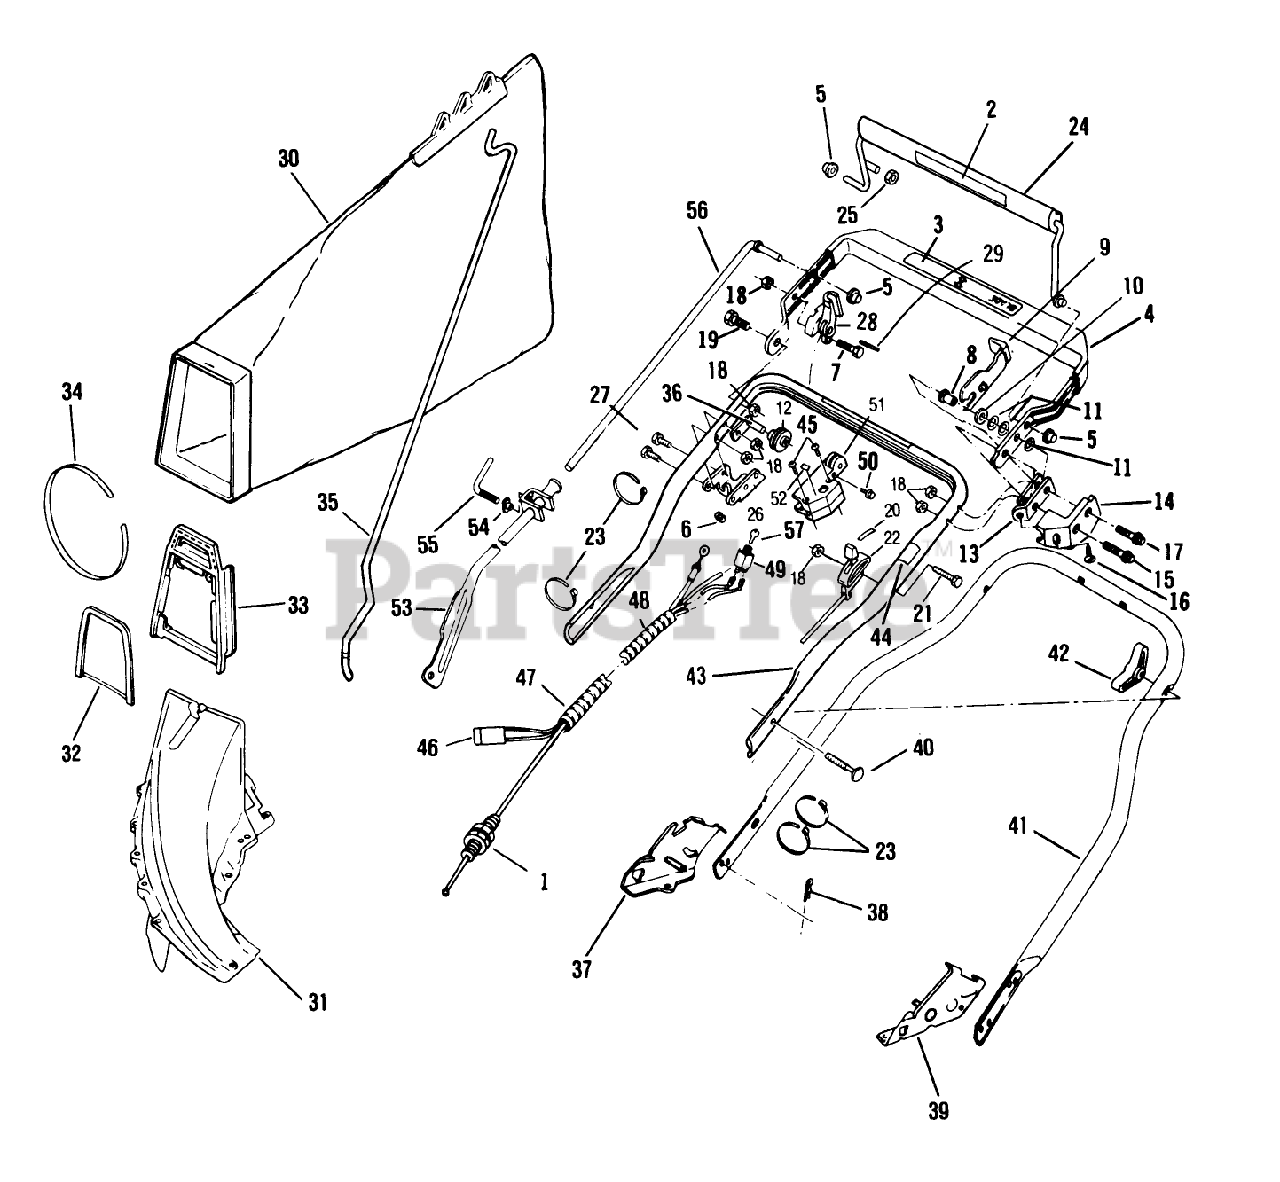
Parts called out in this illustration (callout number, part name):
1	CONTROL CABLE
6	RET. RING
8	SPACER
10	WASHER M
12	PULLEY PL
13	DOWN STOP
14	LOCKOUT GUARD
15	BOLT SHOU
16	SCREW F
17	SCREW
18	LOCKNUT E
19	BOLT
22	CONTROL THROT WES
25	NUT ACORN
28	CAM HOFFER
30	ORDER 89816 THRU WHOLE GD
32	CHUTE BRACE
33	CHUTE - ADAPTER
35	ROD GRASSBAG
37	BRACKET ASM - HANDLE, SP, RH
38	HAIR PIN
39	BRACKET ASM - HANDLE, SP, LH
40	BOLT QUALITY
42	NUT-WING
43	HANDLE SECTION
45	SCREW LAWRENCE
53	CONTROL LEVER AY
56	CONTROL ROD
